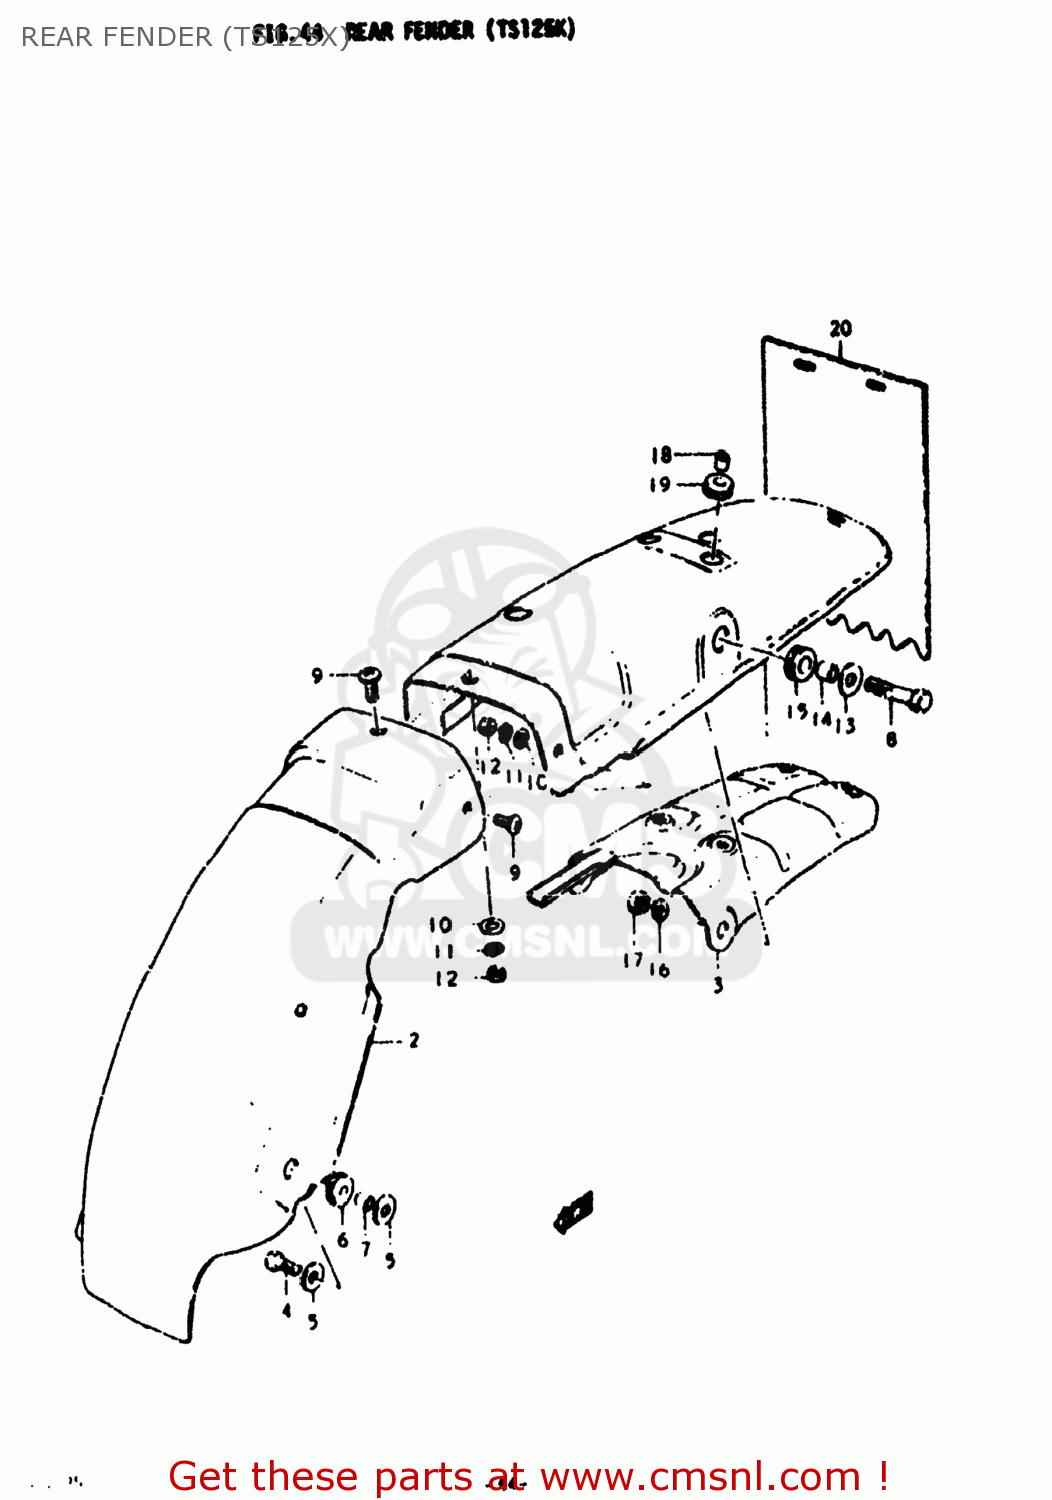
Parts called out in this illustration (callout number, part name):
1	FENDER,REAR
2	FENDER,REAR
3	REINFORCEMENT,REAR FENDER
4	BOLT
5	WASHER (6.5X20X1.2)
6	CUSHION
7	SPACER(6.8X10X24.2)
8	BOLT
9	SCREW
10	WASHER 5MM
11	LOCK WASHER
12	NUT
13	WASHER(10.3X25X1.5
14	SPACER
15	CUSHION
16	LOCK WASHER
17	NUT
18	WASHER
19	CUSHION
20	MUD GUARD,REAR FENDER
